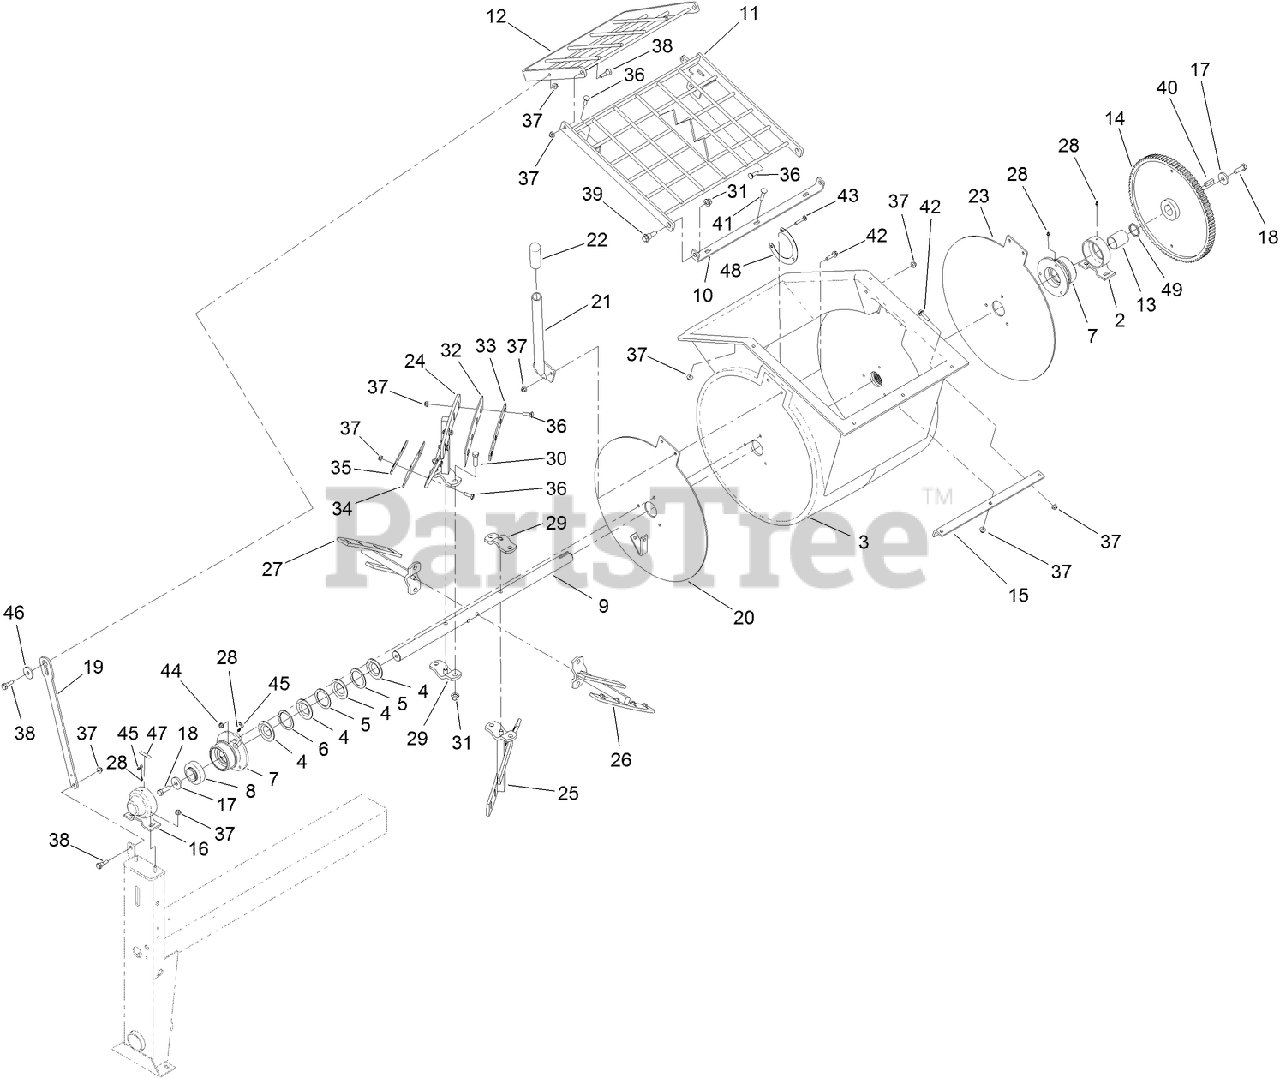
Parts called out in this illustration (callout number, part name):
2	TRUNNION
4	SEAL-DRUM
5	WASHER-FLAT
6	WASHER-SPLIT
7	HOUSING-BEARING
8	BEARING-BALL
9	SHAFT-DRUM
10	MOUNT-GUARD
11	GUARD-STATIONARY
12	GUARD-DRUM
13	SPACER-SHAFT, DRUM
14	GEAR-94 TEETH
15	SUPPORT-GUARD
16	TRUNNION-CAPPED
17	WASHER-FLAT
18	SCREW-HH
19	BAR-GUARD, LIFTER
20	END-DRUM
22	GRIP-HAND
23	END-DRUM
28	FITTING-GREASE
30	SCREW-HH
31	NUT-LOCK
32	BLADE-RUBBER, LONG
33	BAR-BACKER, LONG
34	BLADE-RUBBER, SHORT
35	BAR-BACKER, SIDE
36	BOLT-CARR
37	NUT-HF, NI
38	BOLT-SHOULDER
39	SCREW-SHOULDER, HHF
40	KEY-SQUARE
41	SCREW-CARR
42	SCREW-HHF
43	SCREW-CARR
44	NUT-HF, NI
45	CAP-PLUG
46	Washer-Thrust
47	DECAL-GREASE
48	SPACER-BOLT
49	SPACER-SHAFT, DRUM
